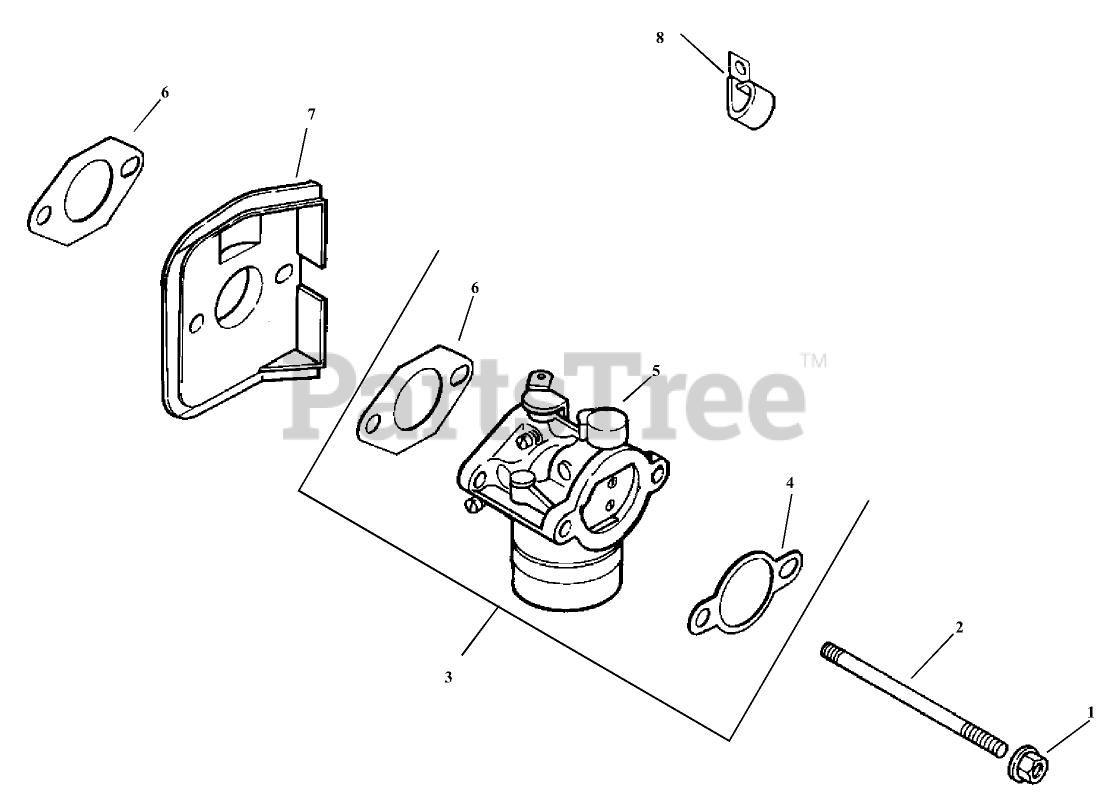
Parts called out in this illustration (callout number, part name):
1	NUT-FLANGE (M6X1.0)
2	Stud (M6x1.0x116)
3	Kit-Carburetor w/Gaskets (Incl. 4-6)
4	Gasket-Base, Air Cleaner
5	Carburetor ASM
6	Gasket-Carburetor
7	Deflector-Heat
8	CLIP-CABLE
